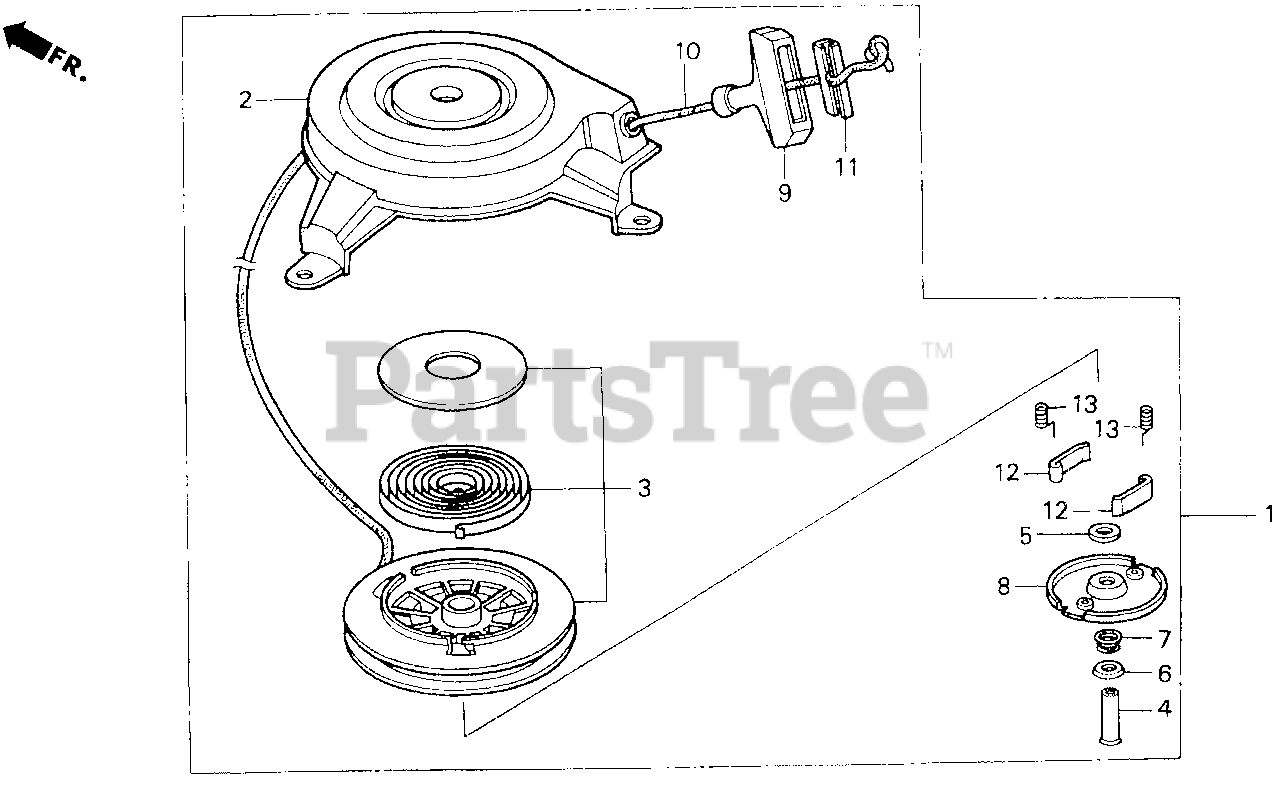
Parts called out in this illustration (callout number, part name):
1	STARTER ASSY., RECOIL
2	HOUSING ASSY.
3	PULLEY & SPRING ASSY.
4	PIN, CENTER
5	PLATE A, FRICTION
6	PLATE B, FRICTION
7	SPRING, FRICTION
8	RETAINER
9	HANDLE
10	ROPE, RECOIL STARTER
11	HANDLE, REINFORCEMENT
12	RATCHET, STARTER
13	SPRING, DOG
